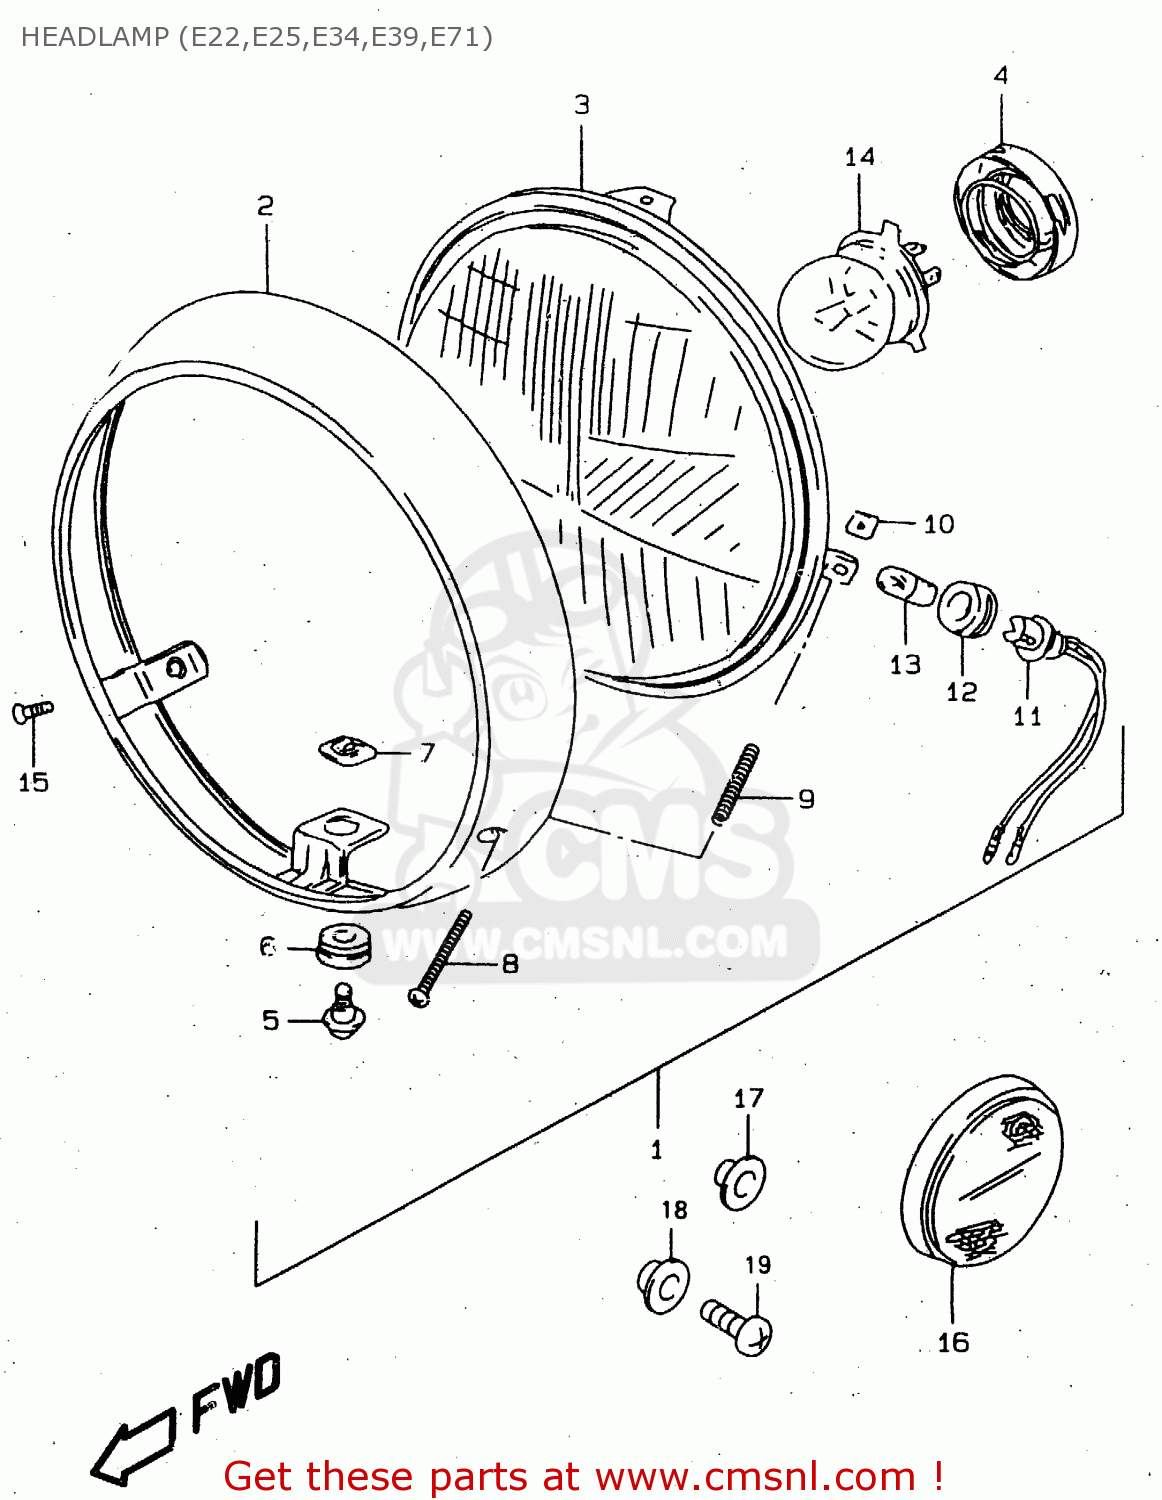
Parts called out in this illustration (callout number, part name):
1	HEADLAMP ASSY
2	RIM
3	LAMP UNIT
4	HOLDER,BULB
5	SCREW,MOUNTING
6	CUSHION
7	NUT
8	SCREW
9	SPRING
10	NUT
11	SOCKET
12	JOINT,RUBBER
13	BULB(12V4W)
14	BULB(12V45/40W)
15	SCREW
16	REFLEX REFLECTOR ASSY,FR SIDE
17	WASHER
18	WASHER
19	SCREW
